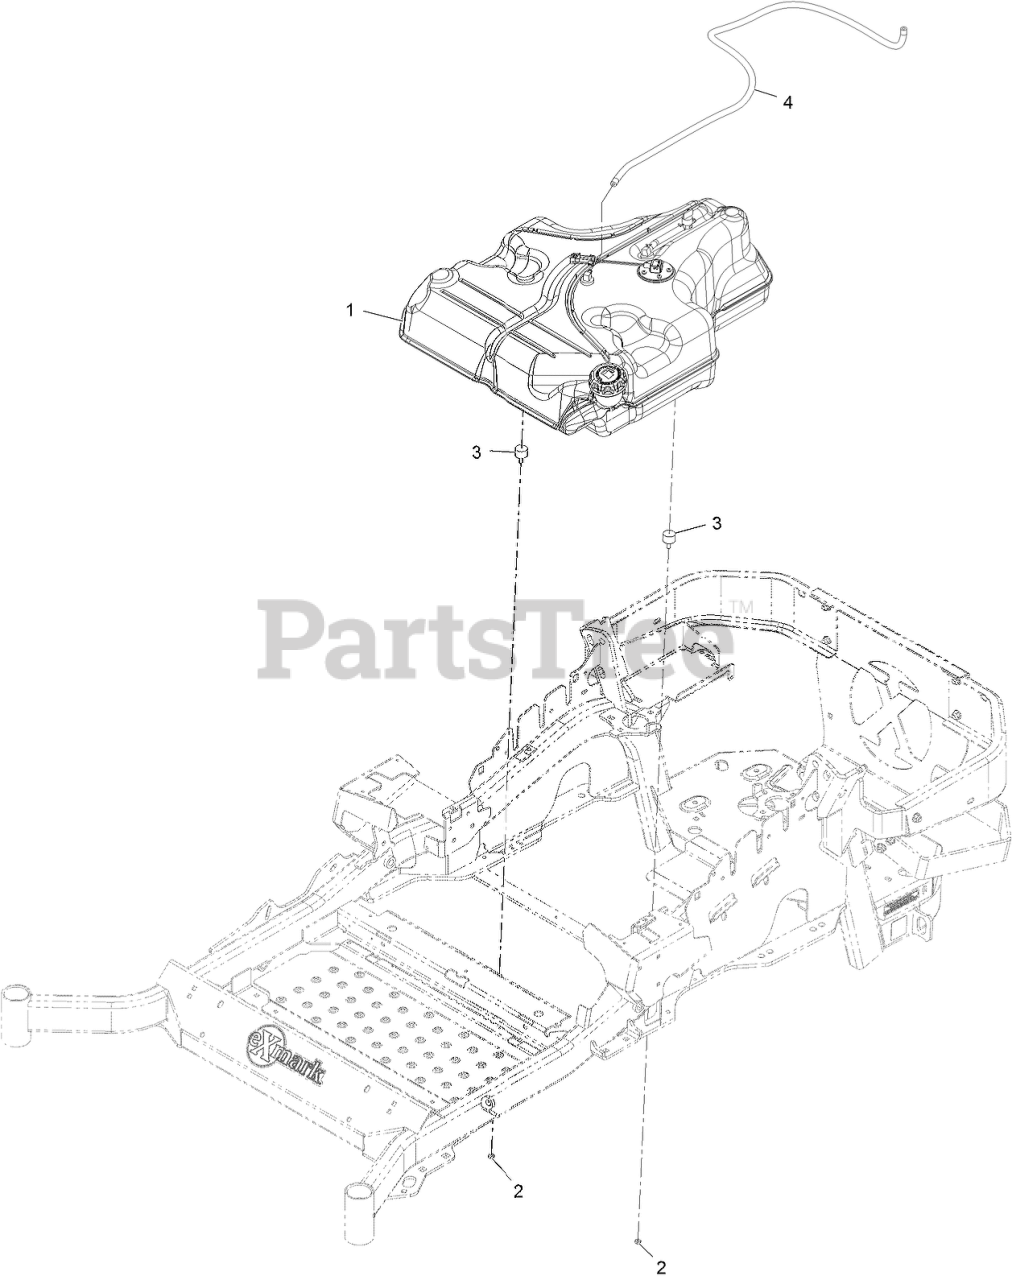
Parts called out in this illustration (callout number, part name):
1	FUEL TANK ASM
2	NUT-JAM
4	Hose-Fuel (.188 X .406 X 40.00)
